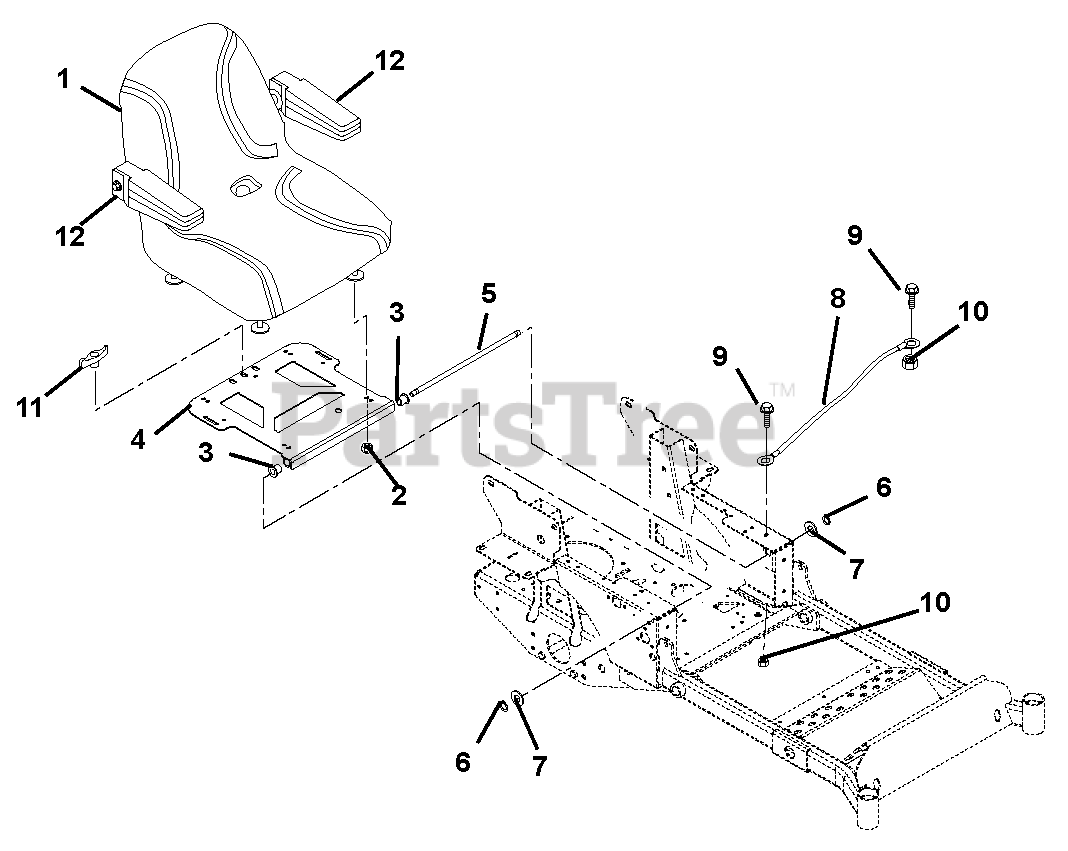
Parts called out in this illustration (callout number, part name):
2	Nut, Nyloc Flange 5/16-18
3	Bushing, Flange .515 x .750 x .745 x 1.00
4	Seat Pivot Mount
5	Rod, Seat Frame Pivot
6	Ring, Retaining External .50 x .05
7	Washer, Flat Steel .531 x 1.00 x .063
8	Cable, Hood
9	Bolt, Hex .25-20 x .75 Grade 5
10	Nut, Nyloc Flange .25-20
11	Knob, Wing .312-18
12	Kit, Consumer Arm Rest
